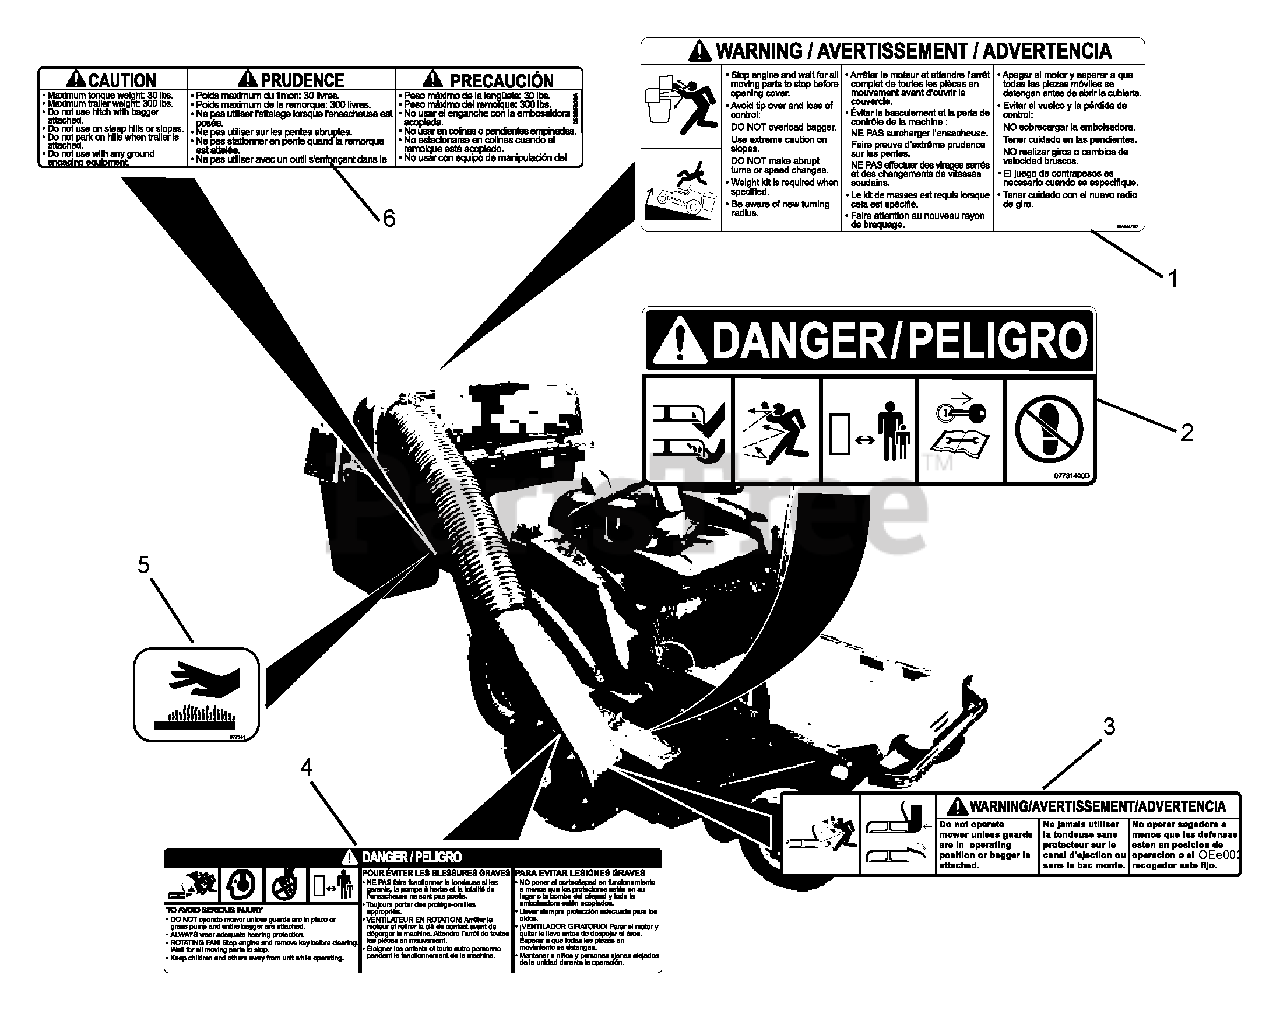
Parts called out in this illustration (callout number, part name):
1	Bagger Cover Decal
2	Mower Pan Danger Decal
3	Warning Decal
4	Grass Pump Caution Decal
5	Decal, Hot Surface
6	Decal, Trailer Hitch
